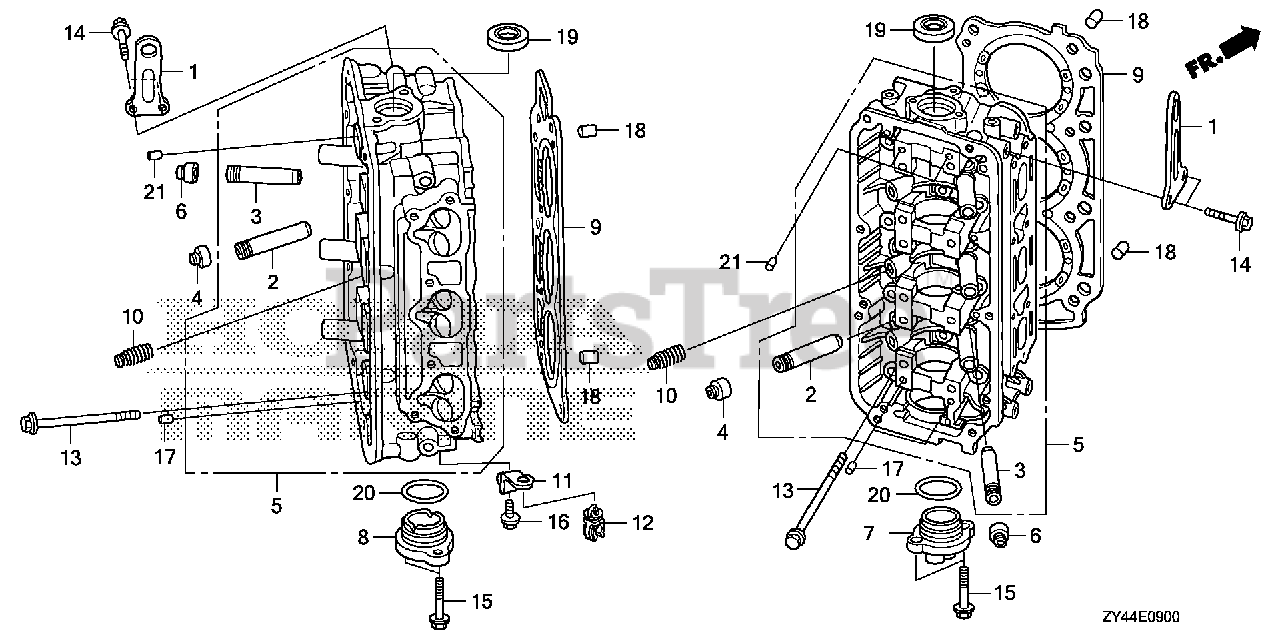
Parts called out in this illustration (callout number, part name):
1	HANGER, ENGINE
2	GUIDE, VALVE (OVER SIZE)
3	GUIDE, EX. VALVE (OVER SIZE)
4	SEAL A, VALVE STEM (NOK)
5	CYLINDER HEAD *NH8* (DARK GRAY)
6	SEAL B, VALVE STEM (NOK)
7	COVER, R. CAMSHAFT THRUST
8	COVER, L. CAMSHAFT THRUST
9	GASKET, CYLINDER HEAD (NIPPON LEAKLESS)
10	MOTION, LOST
11	BRACKET, FUEL TUBE
12	CLIP, THROTTLE WIRE
13	BOLT-WASHER (12X163)
14	BOLT, FLANGE (8X20)
15	BOLT, FLANGE (8X28)
16	BOLT, FLANGE (8X16)
17	PIN, DOWEL (6X10)
18	PIN, DOWEL (16X22)
19	OIL SEAL (39X53X8) (NOK)
20	O-RING (48.5X2.4)
21	PIN B, DOWEL (6X10)
